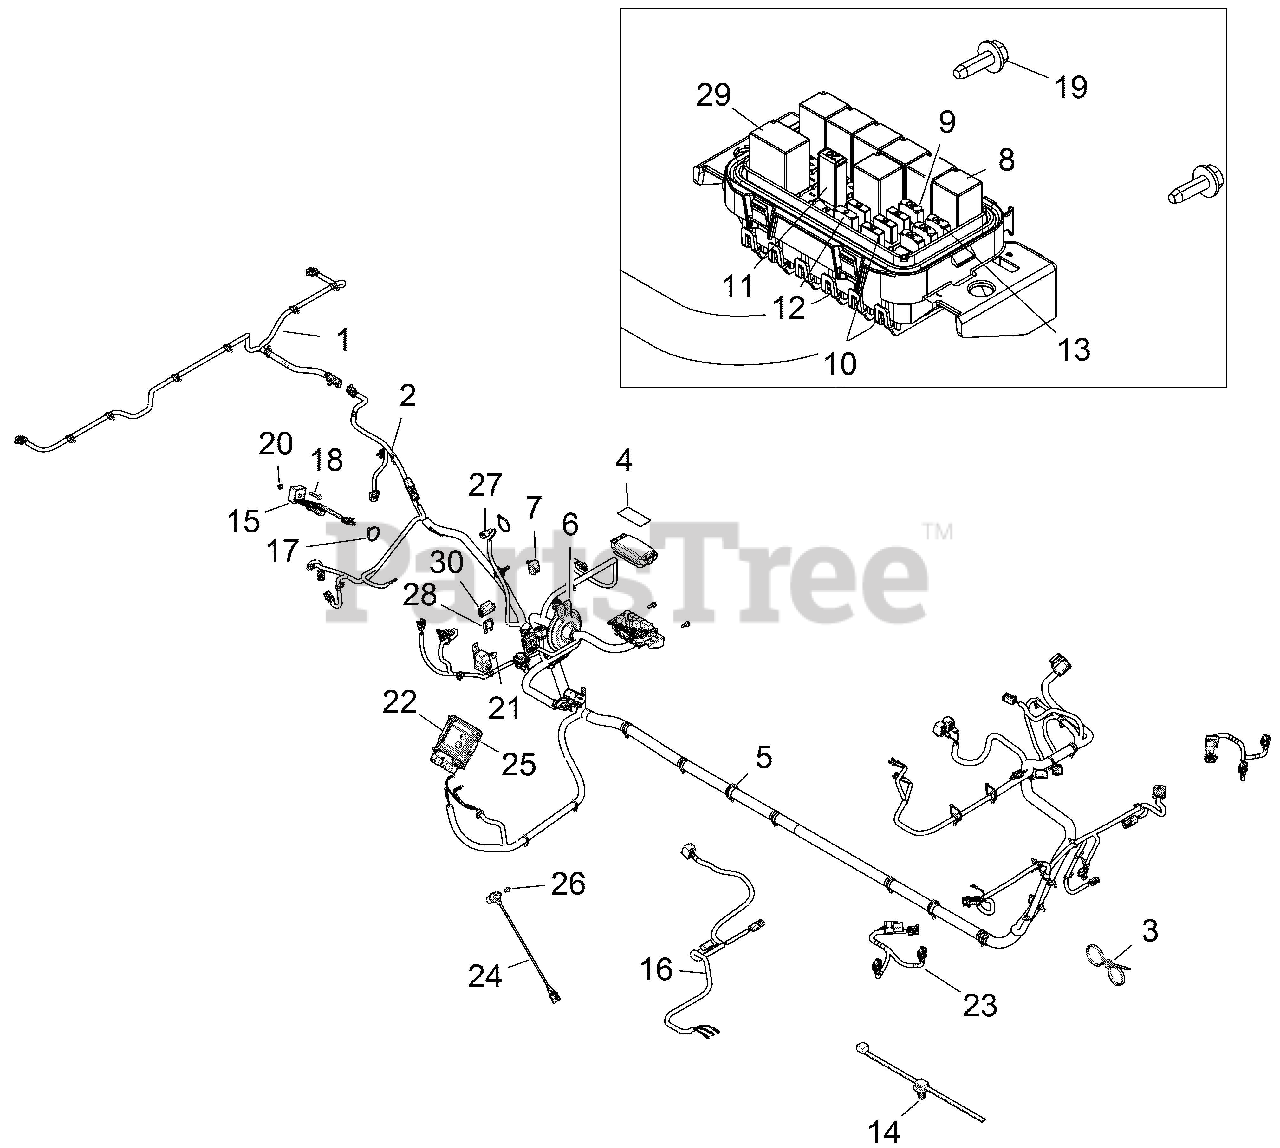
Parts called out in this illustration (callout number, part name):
1	HARNESS-BOX-ARIENS SPLY
2	HARNESS, CHASSIS
2	KIT, FUSIBLE LINK, 2MM
2	KIT, FUSIBLE LINK, 1MM
2	KIT, FUSIBLE LINK, .8MM
3	CABLE TIE
4	DECAL, FUSE BLOCK
5	CLIP-ROUTING
6	GROMMET-CHASSIS HARNESS
7	COVER-DIAGNOSTIC,W/CLIP
8	RELAY-SPST,SERIES 303,SEALED
9	FUSE,PARK,20 AMP,(10)
10	FUSE, MINI BLADE, 15 AMP
11	BREAKER-CIRCUIT,20 AMP
12	FUSE-5A,MINI BLADE
13	FUSE,MAIN,30 AMP,(10)
14	CLIP-ROUTING
15	RELAY, SOLID STATE,9A,LONG LD
16	HARNESS-BOX,LIFT
17	CABLE TIE (10)
18	BOLT-M6X1.0X35,HXFLG/SH-OLV D
19	SCR-M6X1.0X20,HXHD,FLG,TDFM,BL
20	NUT-M6X1.0,FLG-NYLOC-OLIVE D
21	CLIP, PLASTIC DART, NYLON
22	SERVICE ECU, ALL MY11 800 DOM
23	HARNESS-HEADLIGHT,ARIENS
24	SENSOR-CRANK POSITION
25	SCR-#10X1/2-HI/LO-PN-T25,TRX-M
27	BOOT, OIL PRESSURE SWITCH
28	TVS, 30VOLT
29	RELAY-SPDT,SERIES 301,SEALED
30	CLIP, X-MAS-TREE
